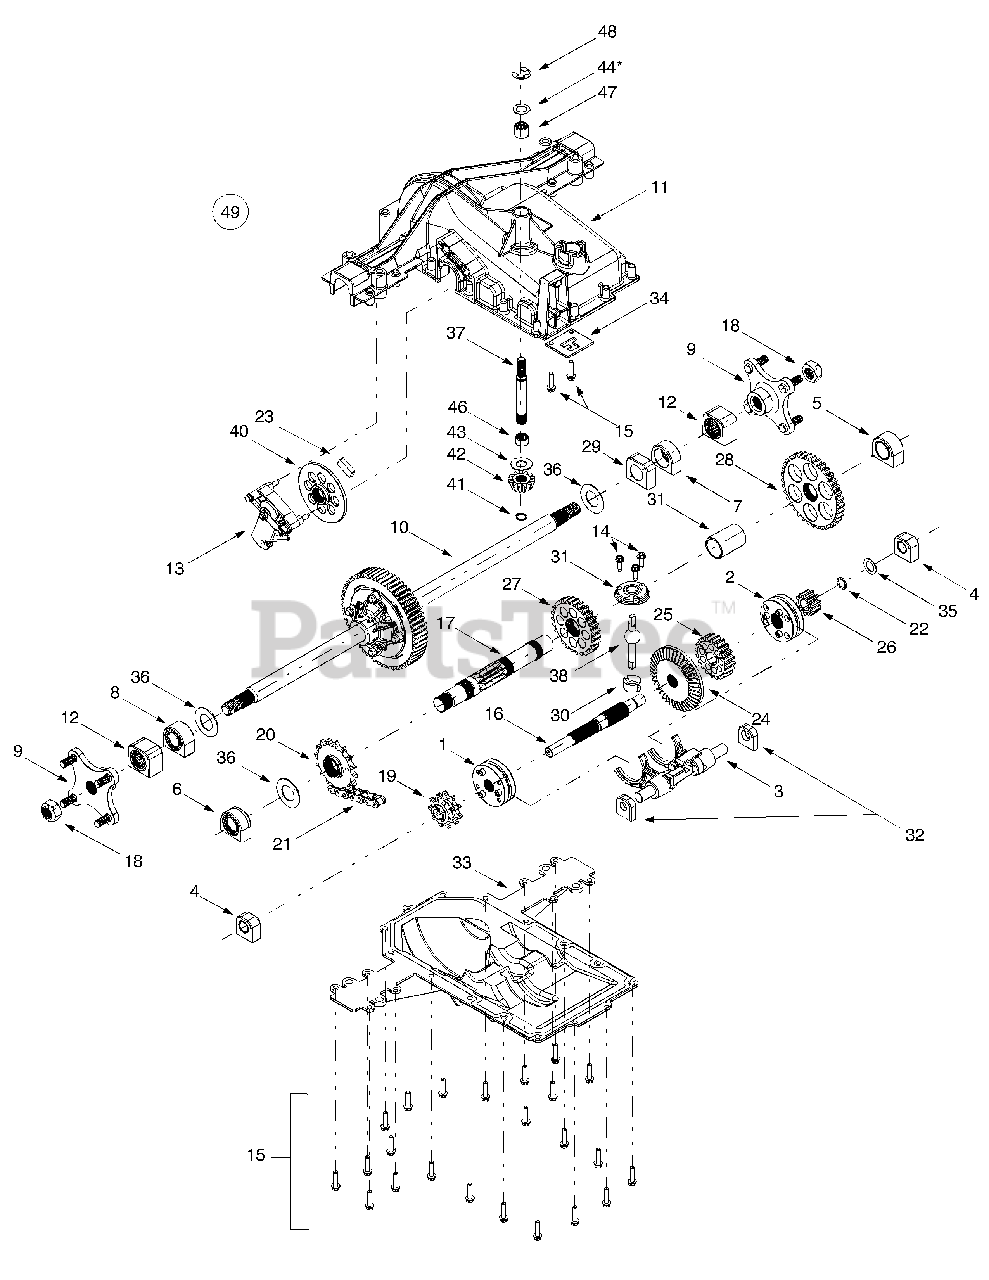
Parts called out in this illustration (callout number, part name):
1	Reverse Collar Assembly
2	Hi-Lo Collar Assembly
3	Shift Fork Assembly
4	Detent Block Assembly
5	Output Bearing Block Assembly
6	Output Seal Bearing Block Assembly
7	Inboard Sealed Axle Block Assembly
8	Inboard Sealed Axle Block Assembly
9	Wheel Hub Assembly, spline
10	Differential Axle Assembly
11	Upper Housing
12	Axle Bearing Block Assembly
13	Brake Assembly
14	Self-tapping Screw, 1/4-20 x .75
15	Self-tapping Screw, 1/4-20 x 1.0
16	Drive Shaft
17	Output Shaft
18	Nut, 3/4-16
19	9-tooth Sprocket
20	16-tooth Sprocket
21	22-link Chain, .625
22	External Snap Ring
23	Brake Pad
24	41-tooth Bevel Gear
25	20-tooth Spur Gear
26	10-tooth Spur Gear
27	27-tooth Spur Gear
28	37-tooth Spur Gear
29	Inner Axle Bearing Block
30	Shifter Insert
31	Shifter Cover
32	Shifter Bearing Block
33	Lower Housing
34	Lockout Plate
35	Flat Washer, 5/8 x 1.0
36	Flat Washer, 1.01 x 1.86 x .060
37	Input Shaft
38	Shift Lever
39	Spacer, 1.13 x 1.38 x 1.968
40	Disc Brake
41	Retaining Ring, .56
42	13-tooth Bevel Gear
43	Flat Washer
44	Flat Washer, 5/8 x 1.0 x .030*
46	Needle Bearing
47	Needle Bearing
48	E-ring, .75
49	Transmisssion Assembly Complete
